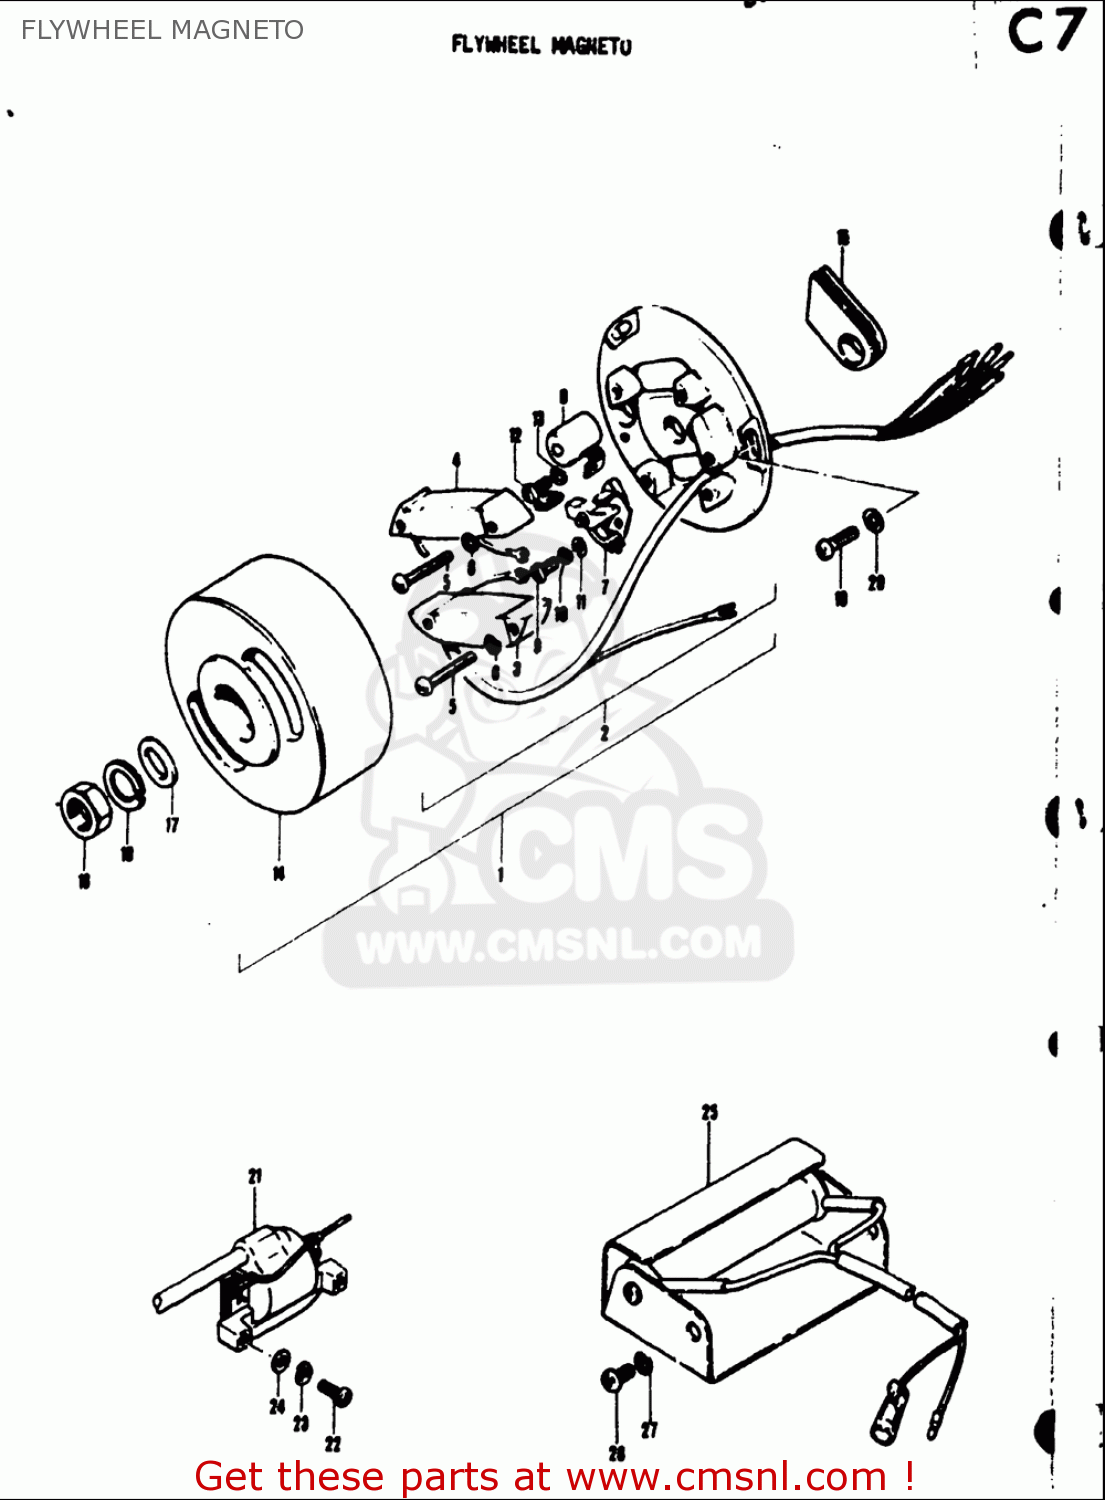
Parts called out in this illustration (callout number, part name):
6	WASHER,LOCK
7	POINT ASSY,CONTACT
8	CONDENSER
9	.SCREW
10	WASHER,LOCK
11	WASHER
12	.SCREW
13	WASHER,LOCK
16	NUT
17	WASHER
18	WASHER,LOCK
19	SCREW
20	WASHER
21	COIL ASSY,IGNITION
22	SCREW
23	WASHER,LOCK
24	WASHER
26	SCREW
27	WASHER,LOCK
